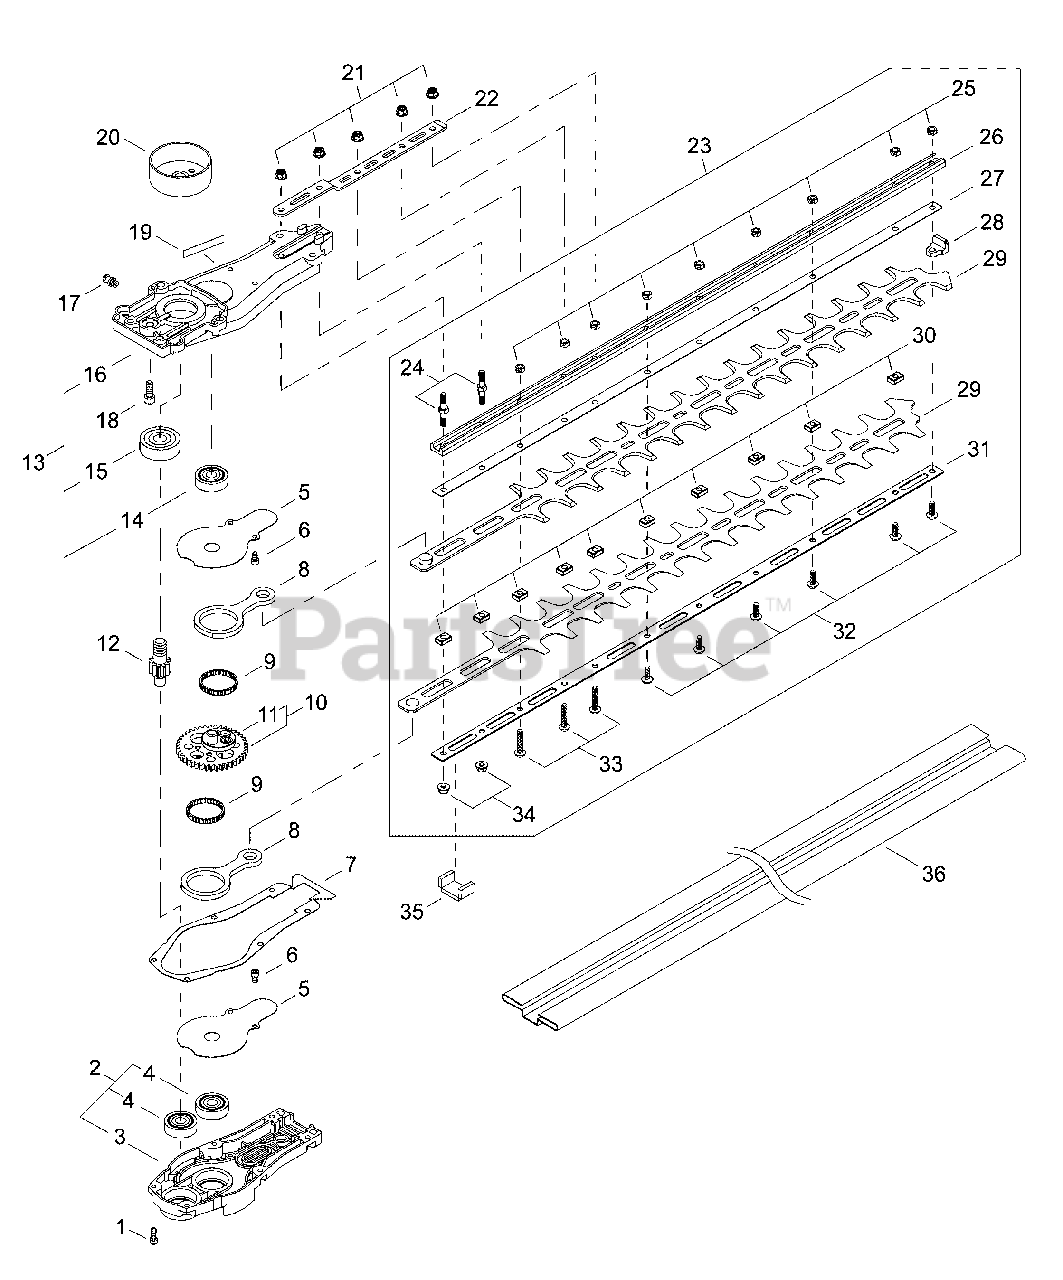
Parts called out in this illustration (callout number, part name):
1	BOLT 4×14
2	COVER ASSY, GEAR CASE
3	COVER, GEAR CASE
4	BEARING, BALL 6200ZZ
5	PLATE, GEAR CASE
6	BOLT 4×8
7	GASKET, GEAR CASE
8	CONROD
9	BEARING, NEEDLE 30
10	CAM GEAR ASSY
11	BOLT M5×6
12	PINION
13	GEAR CASE HOUSING ASSY
14	BEARING, BALL 6301 DDU
15	BEARING, BALL 6200ZZ
16	HOUSING, GEAR CASE
17	FITTING, GREASE
18	BOLT 6×16
19	LABEL, LUBE BLADES
20	DRUM, CLUTCH
21	NUT M5
22	BRACKET, CUTTER
23	CUTTER ASSY, 24"
24	STUD, MOUNTING M5
25	NUT, LOCK M5
26	GUIDE BAR, 24"
27	PLATE, UPPER
28	BLOCK
29	BLADE, 24"
30	SPACER
31	PLATE, LOWER
32	BOLT M5×14
33	BOLT M5×25
34	NUT M5
35	PACKING, FELT
36	SCABBARD 24"
